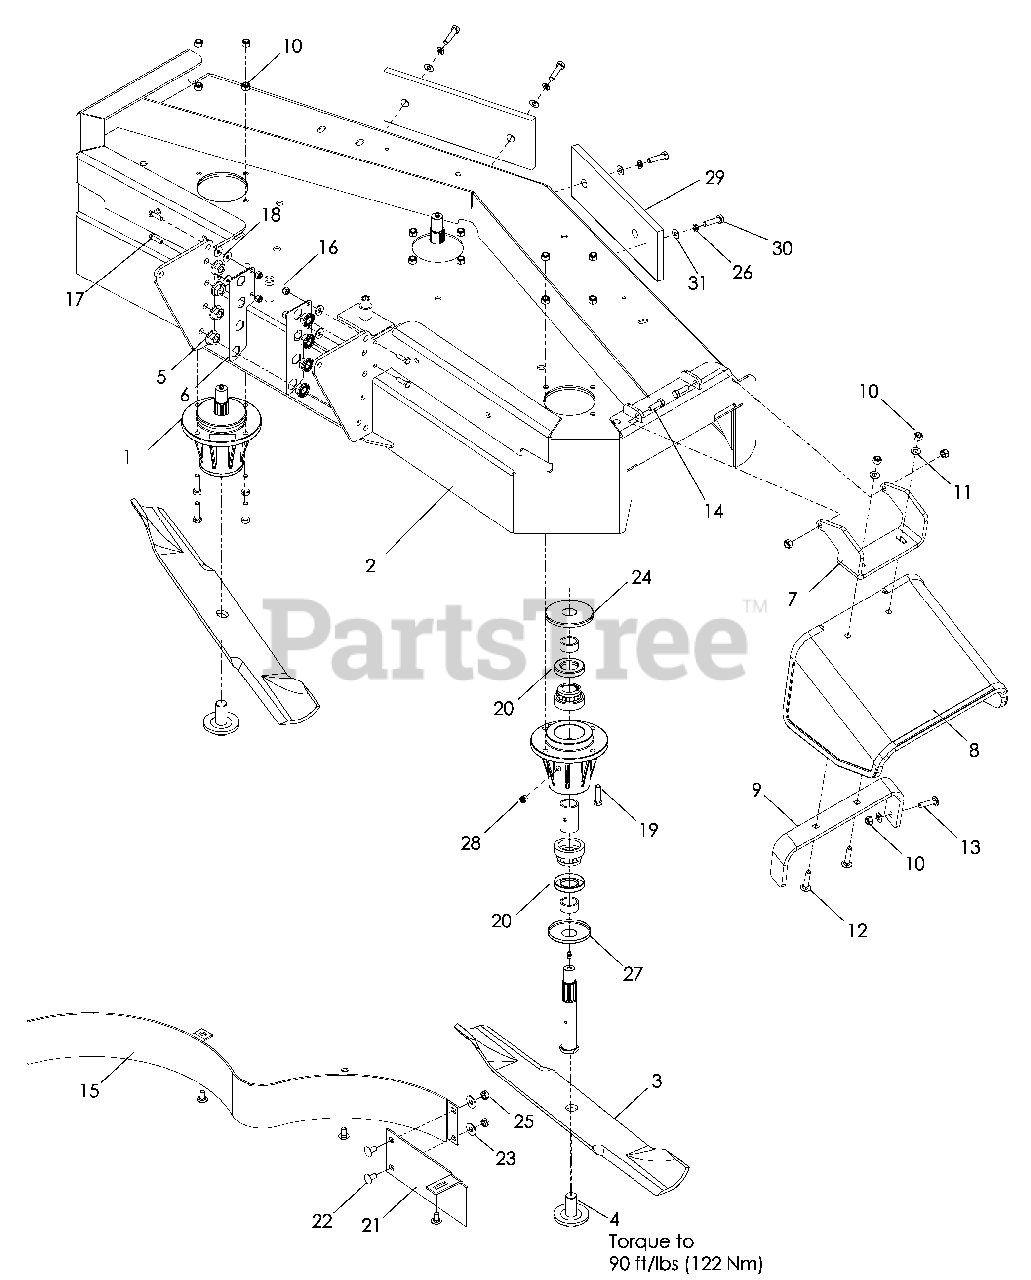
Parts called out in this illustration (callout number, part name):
1	SPINDLE ASSEM
2	DECK W DECALS, 52"
4	BOLT, BLADE
5	NUT, FLANGE, ½-13
6	NUT, PLATE
7	HINGE, CHUTE
8	RUBBER CHUTE
9	REINFORCEMENT, BRKT
10	NUT 5/16-18 HEX NYLOC
11	WASHER 5/16 SAE FLAT
12	RHSNB 5/16-18 x 1½
13	RHSNB 5/16-18 x 1¼
14	HCS 5/16-18 x 1
15	MAIN BAFFLE
16	NUT ¼-20 HEX NYLOC
17	HCS ¼-20 x 7/8
18	WASHER ¼ FLAT
19	HCS 5/16-18 x 1¼
20	SEAL, SHAFT
21	CENTER BAFFLE
22	RHSNB 5/16-18 x 5/8
23	WASHER 5/16 STD FLT
24	DUST CAP, TOP
25	NUT 5/16-18 HEX CTRLK
26	WASHER ½ SLW
27	DUST CAP, BOTTOM
29	WEIGHT, COUNTER
30	HCS ½-13 x 1½
31	WASHER ½ SAE FLAT
